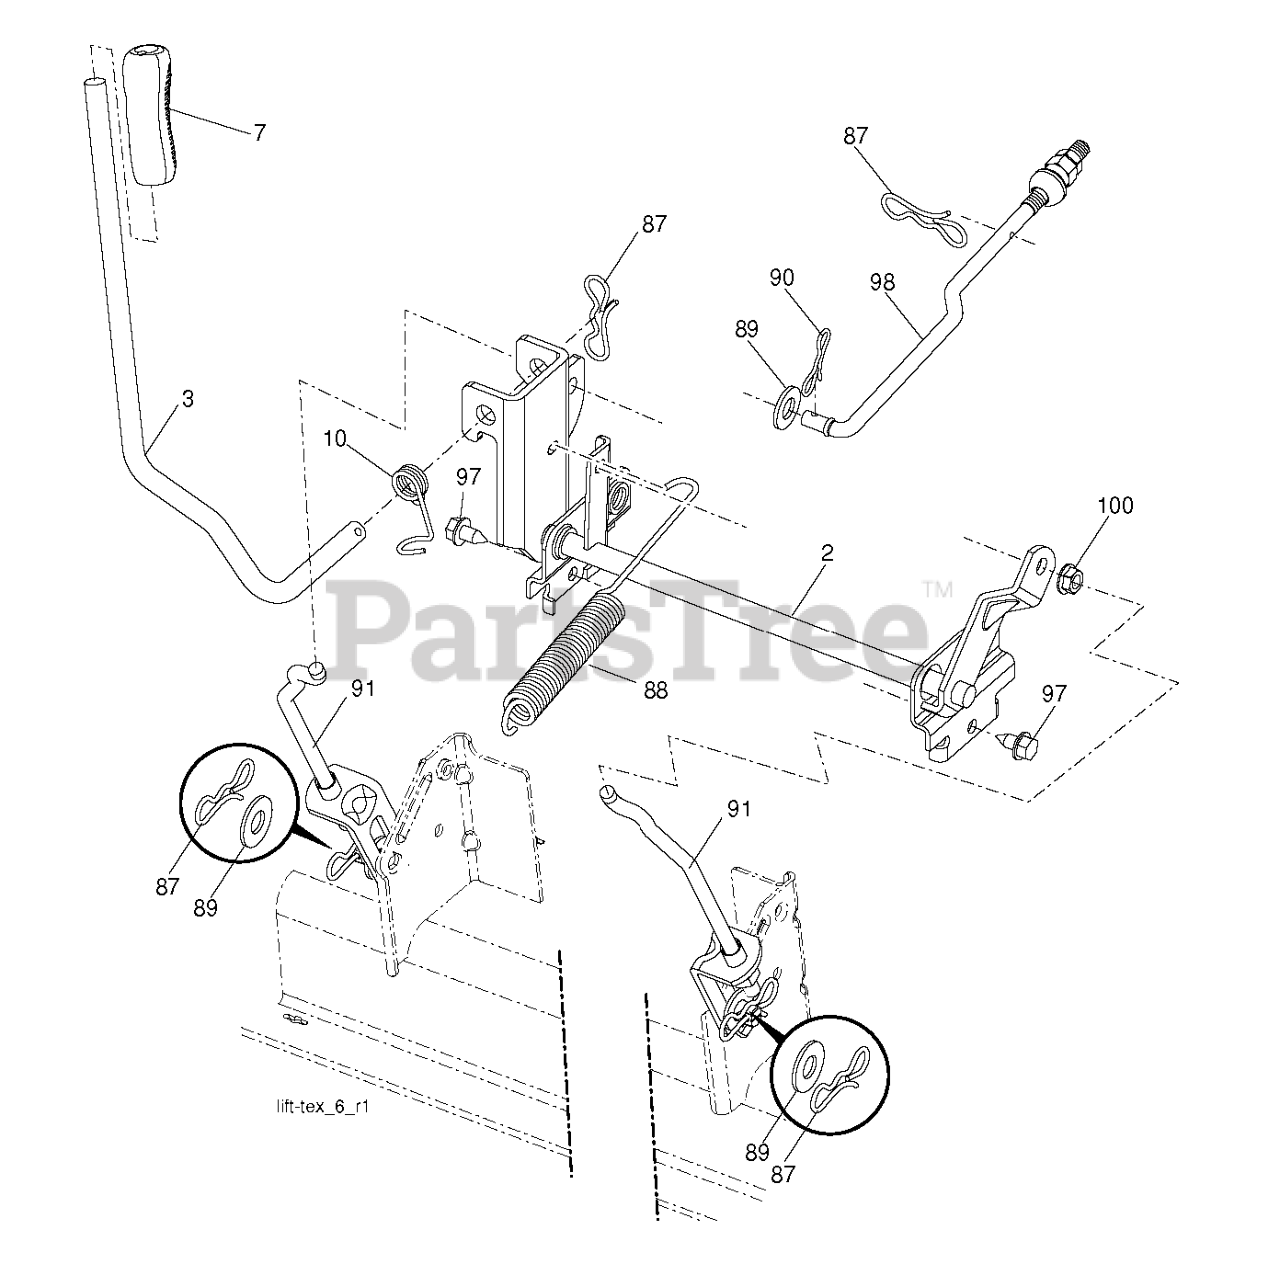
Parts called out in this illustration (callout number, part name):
2	SHAFT.ASM.LIFT.CROSS.H
3	LEVER.LIFT.HANDLE.LT
7	GRIP.HANDLE.LIFT.PVC.BLACK
10	SPRING.TORSION.LIFT.HANDLE
87	PIN.COTTER.7/16.BOW TI.
88	SPRING.LIFT.ASSIST
89	WASHER.CLEAR.ZINC
90	PIN.COTTER.5/16.BOW TI
91	LINK.ASM.LIFT.REAR
97	SCREW, 3/8-16X3/4
98	LINK.ASM.SUSP.FRONT.MW
100	LOCKNUT
